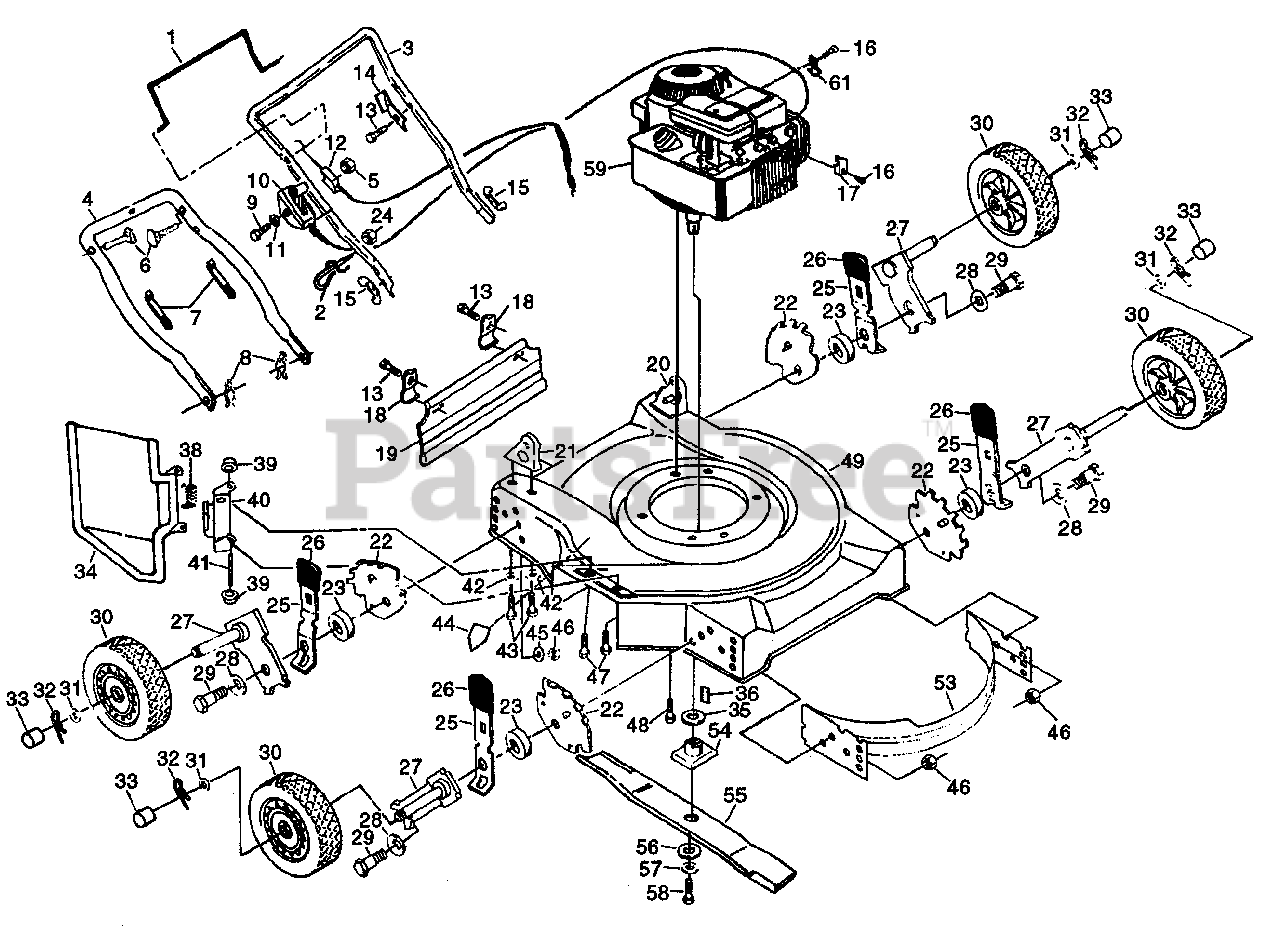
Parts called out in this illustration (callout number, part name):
1	Control Bar (AYP part number)
2	Rope Guide
3	Upper Handle (AYP part number)
4	Lower Handle (AYP part number)
5	Locknut (AYP part number)
6	Handle Bolt 5/16-18 x 1-3/4 (AYP part number)
7	Wire Tie (AYP part number)
8	Hairpin Cotter (AYP part number)
9	Machine Screw 1/4-20 x 2-1/8 (AYP part number)
10	Throttle Control
11	Washer (AYP part number)
12	Engine Zone Control Cable (AYP part number)
13	Hex Washer Head Screw #10-24 x 1/2 (AYP part number)
14	Up-Stop Bracket (AYP part number)
15	Wing Nut (AYP part number)
16	Screw #10 x 5/8 (AYP part number)
17	Cable Clamp (AYP part number)
18	Skirt Bracket (AYP part number)
19	Rear Deflector (AYP part number)
20	Handle Bracket Assembly (Left) (AYP part number)
21	Handle Bracket Assembly (Right) (AYP part number)
22	Wheel Adjusting Bracket (AYP part number)
23	Spacer (AYP part number)
24	Keps Locknut 1/4-20 (AYP part number)
25	Selector Spring (AYP part number)
26	Selector Knob (AYP part number)
27	Axle Arm Assembly (AYP part number)
28	Belleville Washer (AYP part number)
29	Shoulder Bolt (AYP part number)
30	Wheel & Tire Assembly 8.00 x 1-3/4 (AYP part number)
31	Washer (AYP part number)
32	Retainer Clip (AYP part number)
33	Hubcap (AYP part number)
34	Discharge Guard
35	Spacer (AYP part number)
36	Square Key (AYP part number)
38	Torsion Spring (AYP part number)
39	Push On Speed Nut (AYP part number)
40	Housing Bracket Assembly (AYP part number)
41	Hinge Rod (AYP part number)
42	Flat Washer (AYP part number)
43	Screw 5/16-18 x 3/4 (AYP part number)
44	Danger Decal (AYP part number)
45	Washer (AYP part number)
46	Locknut 3/8-16 (AYP part number)
47	Hex Head Thd. Rolling Screw 1/4-20 x 3/4 w/ Sems (AYP part number)
48	Hex Head Thread Rolling Screw 3/8-16 x 1 (AYP part number)
49	Mower Housing
53	Front Baffle (AYP part number)
54	Blade Adapter (AYP part number)
55	Blade 22" (AYP part number)
56	Hardened Washer (AYP part number)
57	Helical Lockwasher 3/8 (AYP part number)
58	Hex Head Screw 3/8-24 x 1-3/8 (Grd. 8) (AYP part number)
61	Clip Cable Throttle (AYP part number)
